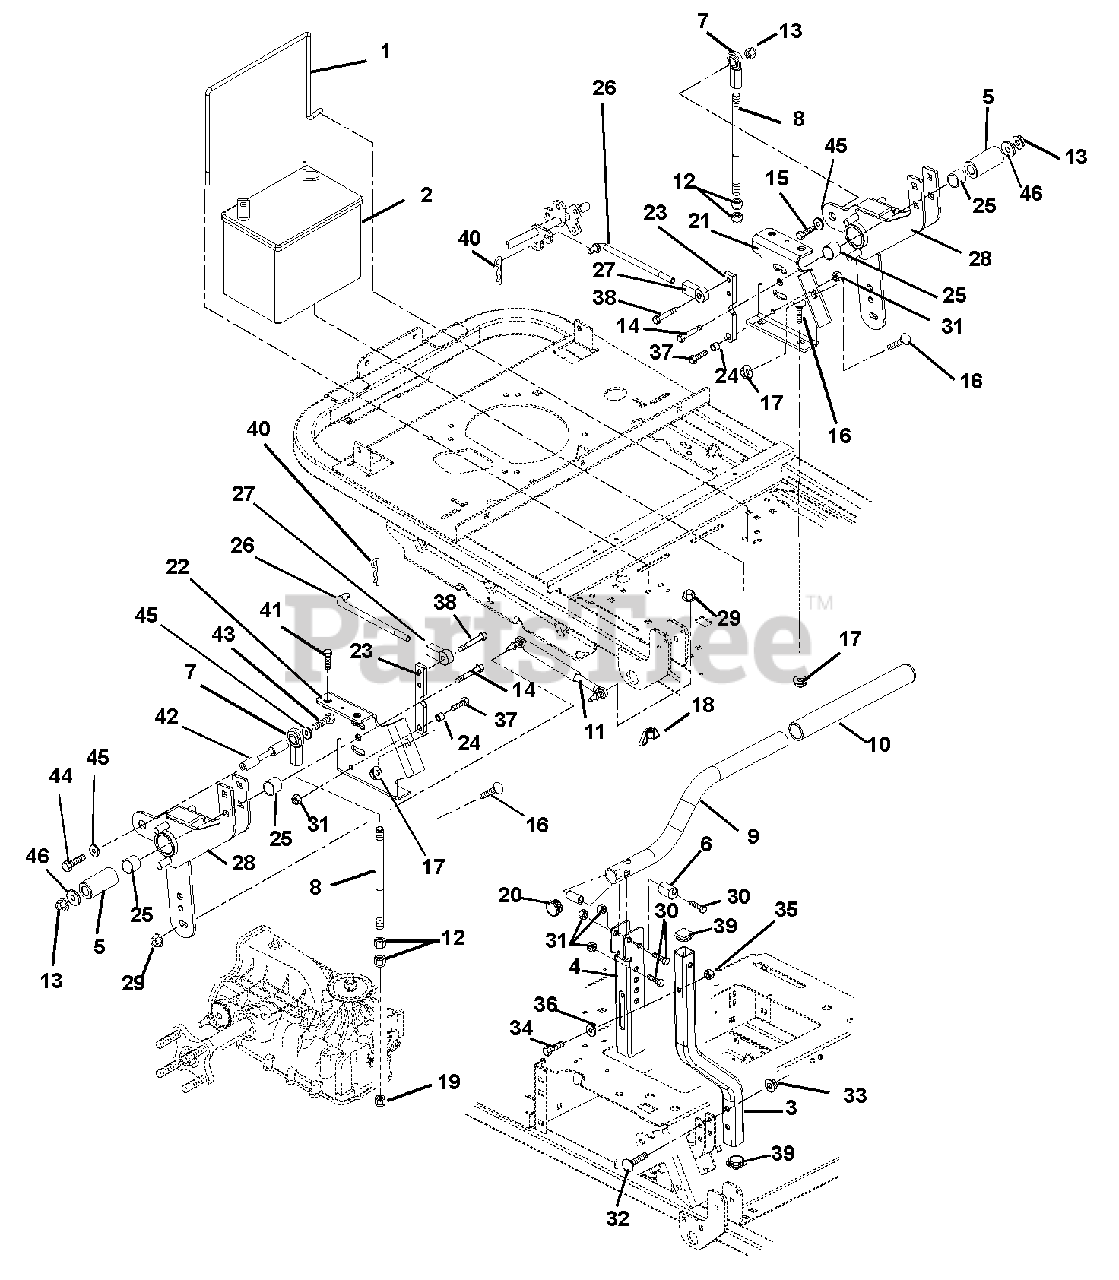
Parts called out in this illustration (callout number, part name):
1	Battery Rod
2	Battery (12 Volt, 250 CCA, 40 Min. Reserve Cap.)
3	Control Arm
4	Channel, Handlebar Adjustment
6	Eccentric
7	Rod End, .50 Right Hand
8	Rod, Transaxle Left Hand
9	Handlebar
10	Grip, Handlebar
12	Nut, Jam .50-20 Grade 2
13	Nut, Locking Top Flange .50-13
14	Bolt, Hex .50-13 x 3.00 Grade 5
15	Bolt, Hex .50-13 x 1.75 Grade 5
16	Bolt, Round Head Square Neck .38-16 x 1.00 Grade 5
17	Nut .38-16 Flange Nyloc
18	Nut, Locking Wing .25-20
19	Nut, Jam Nyloc .50-20 Grade 2
20	Caplug, Handlebar
21	Weldment, Control LH
22	Weldment, Control RH
23	Bracket, Neutral Stop
24	Spacer, Neutral Stop
25	Bearing, 1.00 x 1.12 x .75
26	Link, Brake Rod
27	Rod, End .38 RH
28	Weldment, Steering Control
29	Nut, Locking Top Flange 8 x 1.25
30	Bolt, Hex .31-18 x 1.75 Grade 5
31	Nut, .312-18 Flange Nyloc
32	Bolt, Round Head Square Neck .31-18 x 1.75 Grade 5
33	Nut, Locking Top Flange .31-18
34	Bolt, Hex .25-20 x 1.75 Grade 5
35	Nut, Locking Nylon .250-20
36	Bushing, Flange .265 x .437 x .250 x .750
37	Bolt, Hex .31-18 x 1.25 Grade 5
38	Bolt, Hex .38-16 x .75 Grade 5
39	Caplug, Square
40	Pin, Hair .08 x .18 x 1.18
41	Screw, Cap .38-16 x 2
42	Steering Linkage
43	Bolt, Hex .50-13 x 1.25 Grade 5
44	Bolt, Hex .50-13 x 1.00 Grade 5
45	Washer, Lock .50 x .151
46	Washer, Flat Steel .511 x 1.441 x .125
